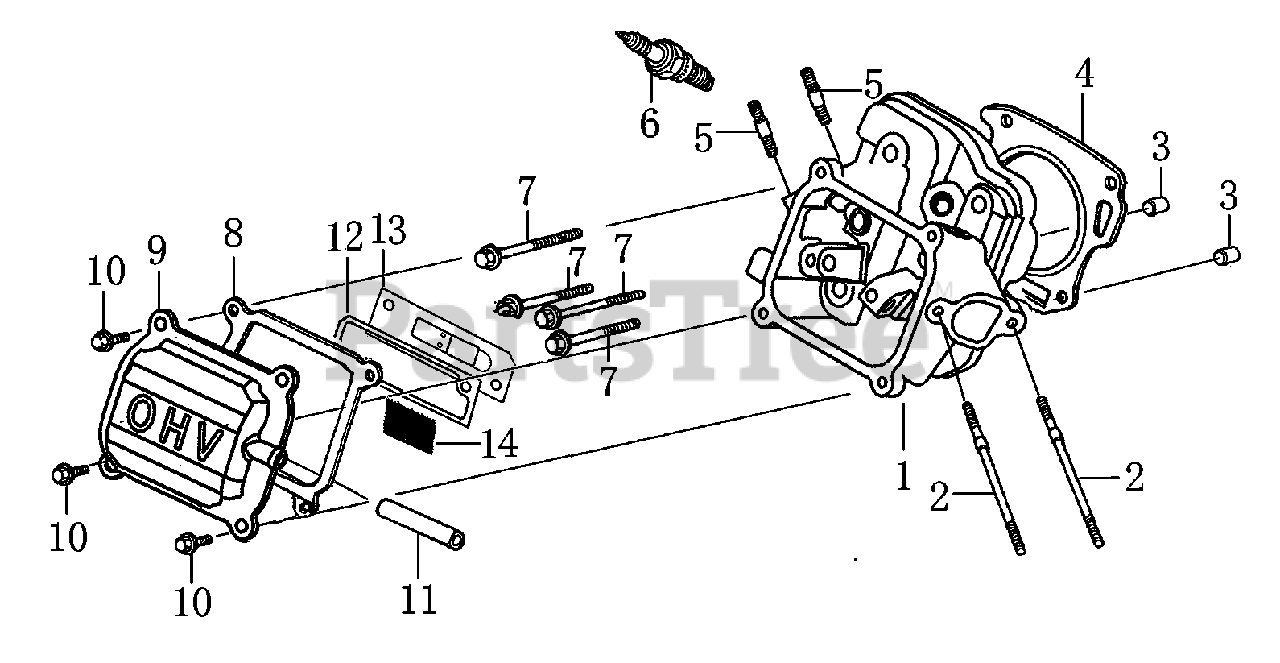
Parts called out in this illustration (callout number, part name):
1	HEAD, CYLINDER
2	BOLT, STUD,IN.
3	PIN, DOWEL
4	GASKET, CYLINDER HEAD
5	BOLT, STUD , EX.
6	PLUG, SPARK
7	BOLT, FLANGE 8*60
8	GASKET, HEAD COVER
9	COVER, HEAD
10	BOLT, FLANGE 6*14
11	TUBE, BREATHER
12	GASKET, BREATHER CHAMBER
13	CAP, BREATHER CHAMBER
14	OIL STRAINER
